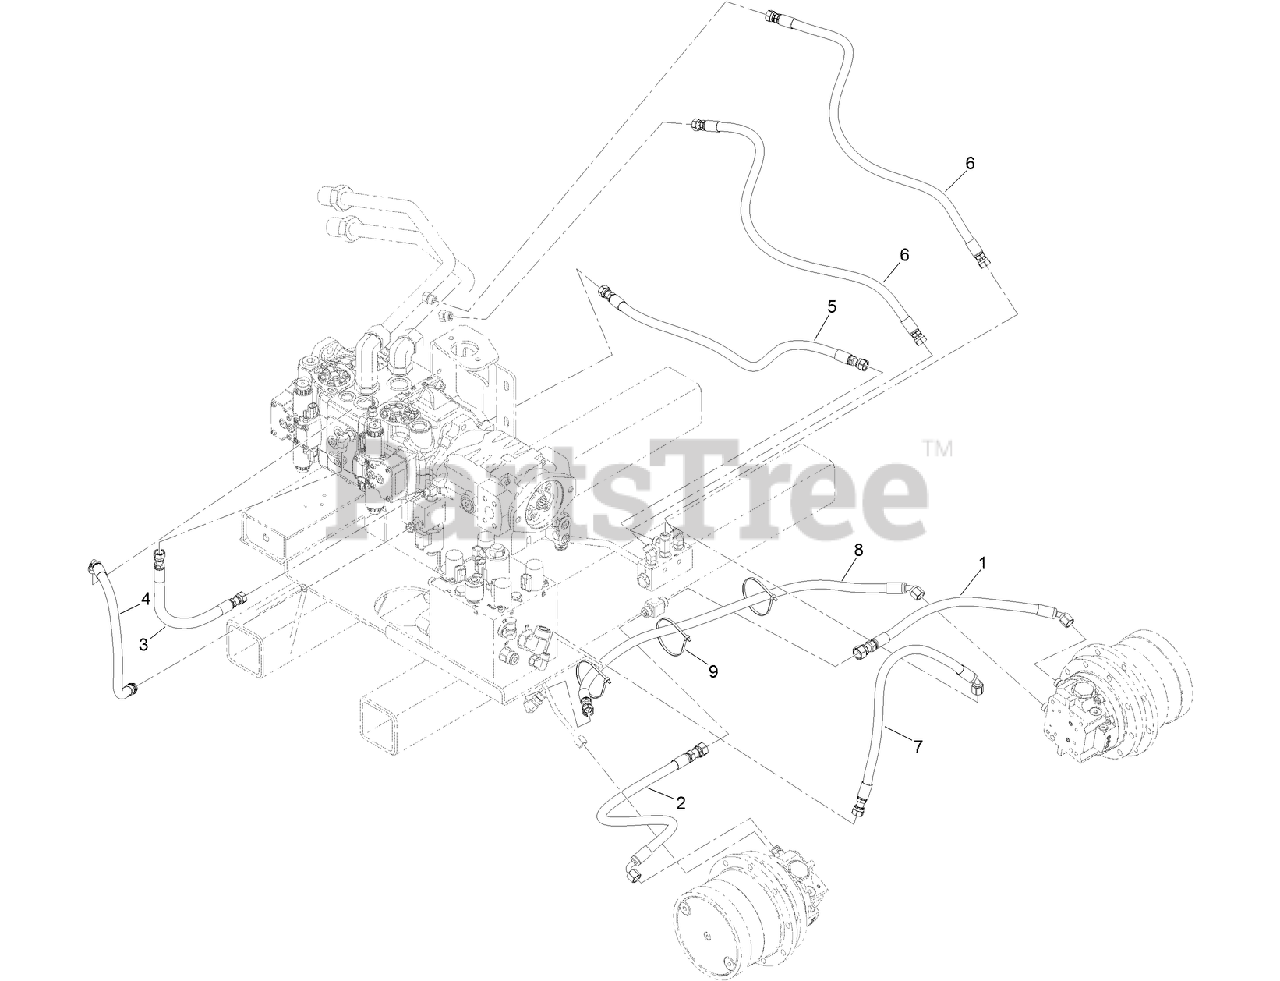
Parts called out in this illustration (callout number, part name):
1	HOSE ASM-HYD
2	HOSE ASM-HYD
3	HOSE ASM-HYD
4	HOSE ASM-HYD
5	HOSE ASM-HYD
6	HOSE ASM-HYD
7	HOSE ASM-HYD
8	HOSE-HYD
9	TIE-CABLE
